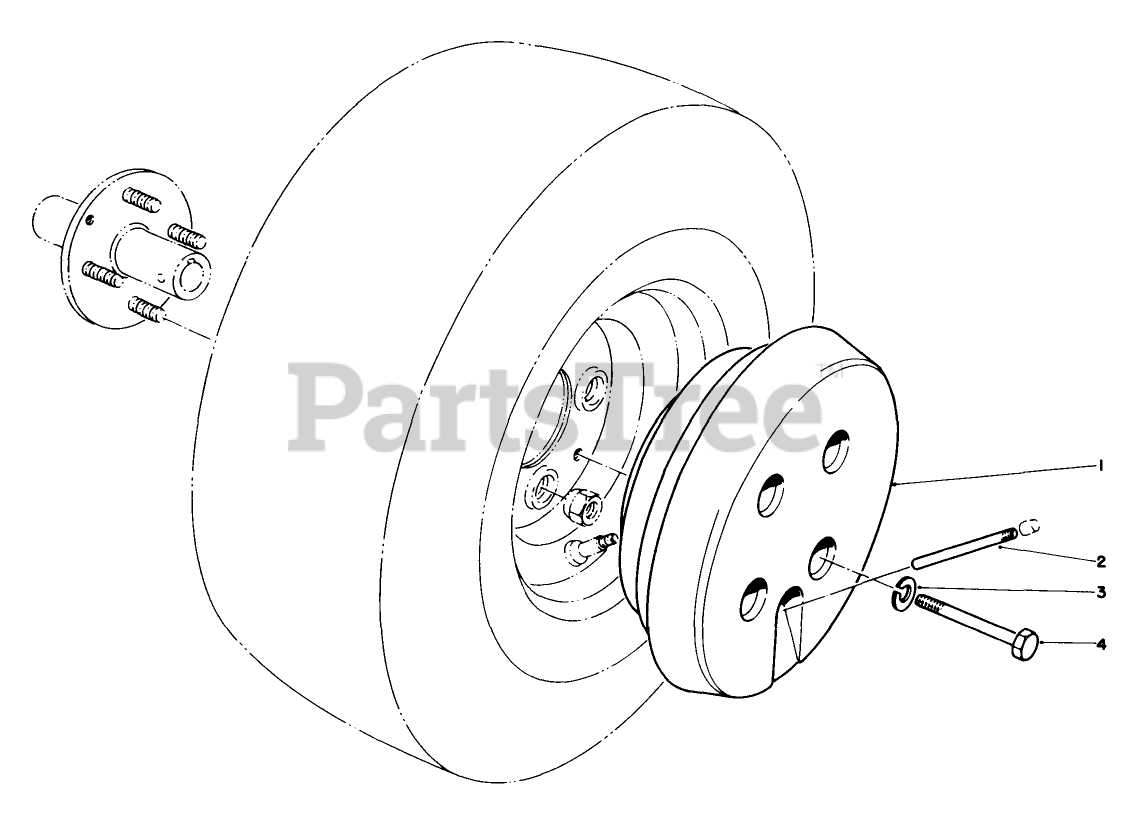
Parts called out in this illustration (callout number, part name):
1	Weight-Wheel
2	VALVE EXTENSION
3	WASHER-LOCK
4	SCREW-HH
